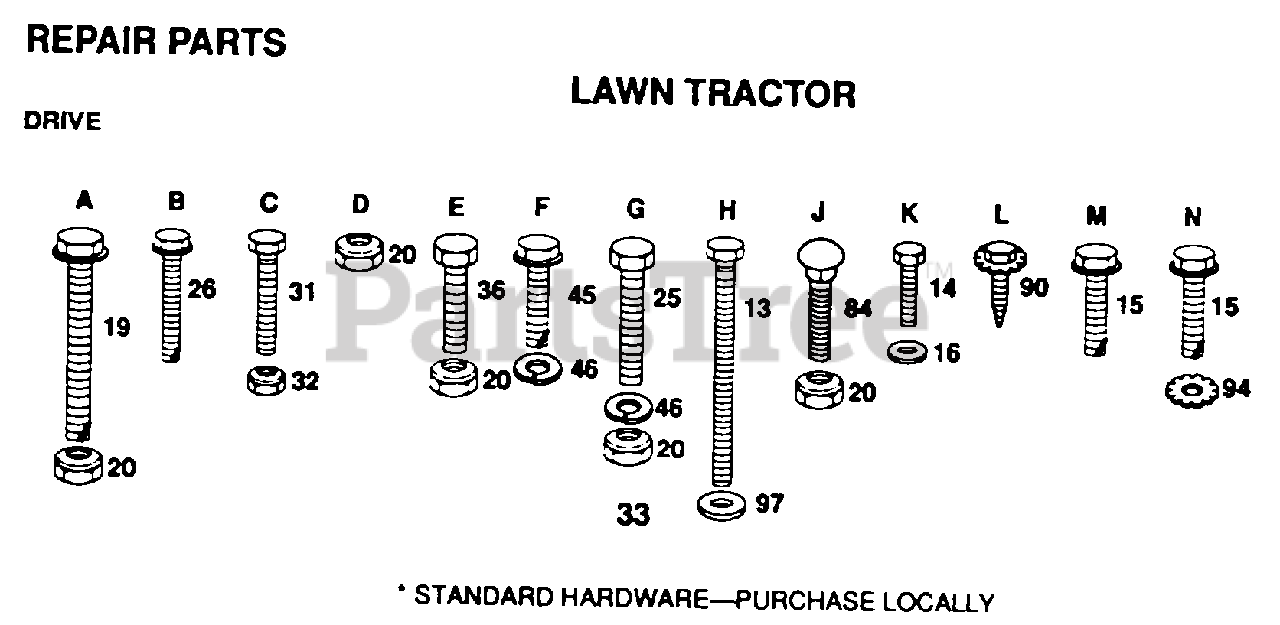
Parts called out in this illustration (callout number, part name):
13	"BOLT,HEX"
14	BOLT
15	SCREW
16	LOCKWASHER
19	BOLT
25	BOLT
26	SCREW
31	BOLT
33	STRAP LOCATOR
45	SCREW
46	WASHER
84	BOLT
94	LOCKWASHER
97	WASHER T
